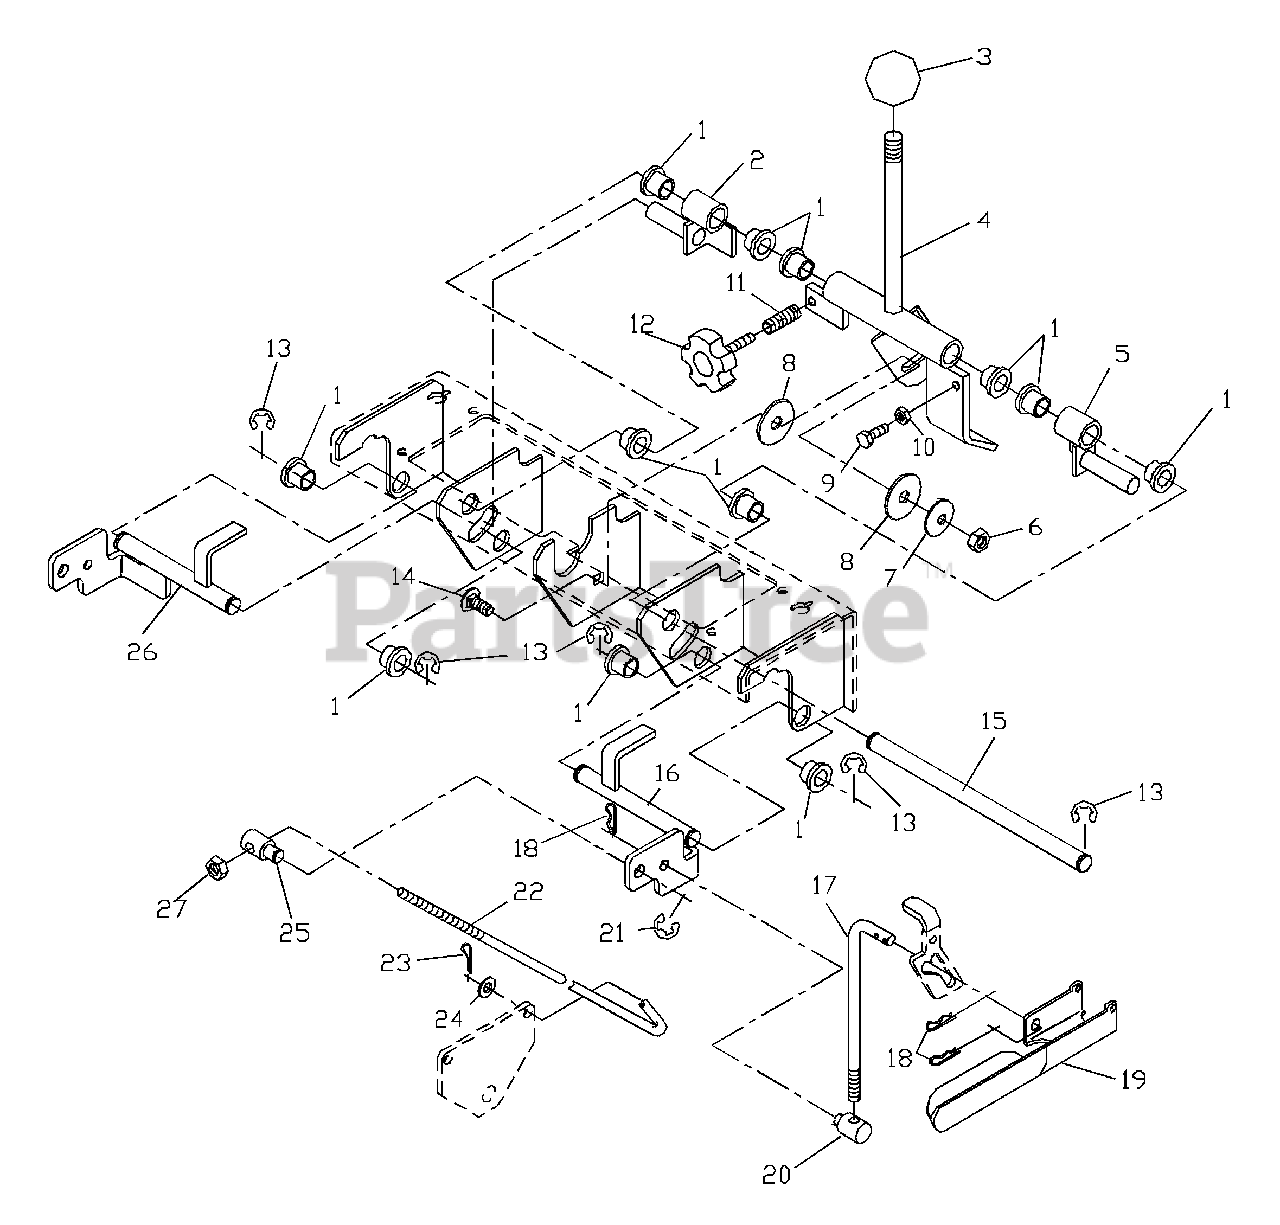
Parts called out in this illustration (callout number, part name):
1	FLANGED NYLON BUSHING
2	TRACK WELDMENT, LT.
4	TRAVEL LEVER
5	TRACK WELDMENT, RT.
6	NUT 5/16C CENTERLOCK
7	CONE WASHER
8	FRICTION WASHER
9	HCS 5/16C X 1
10	5/16 WHIZ NUT
12	ADJUSTMENT KNOB
13	1/2" E-RING
14	RHSNB 5/16C X 1
15	TRAVEL BAR
16	CONTROL WELDMENT, RT.
17	CONTROL LINK
18	HAIR PIN
19	CONTROL LEVER RT.
21	3/8" E-RING
23	3/32 X 3/4 COTTER PIN
24	5/16 WASHER
26	CONTROL WELDMENT LT.
27	NUT 5/16C NYLOC
